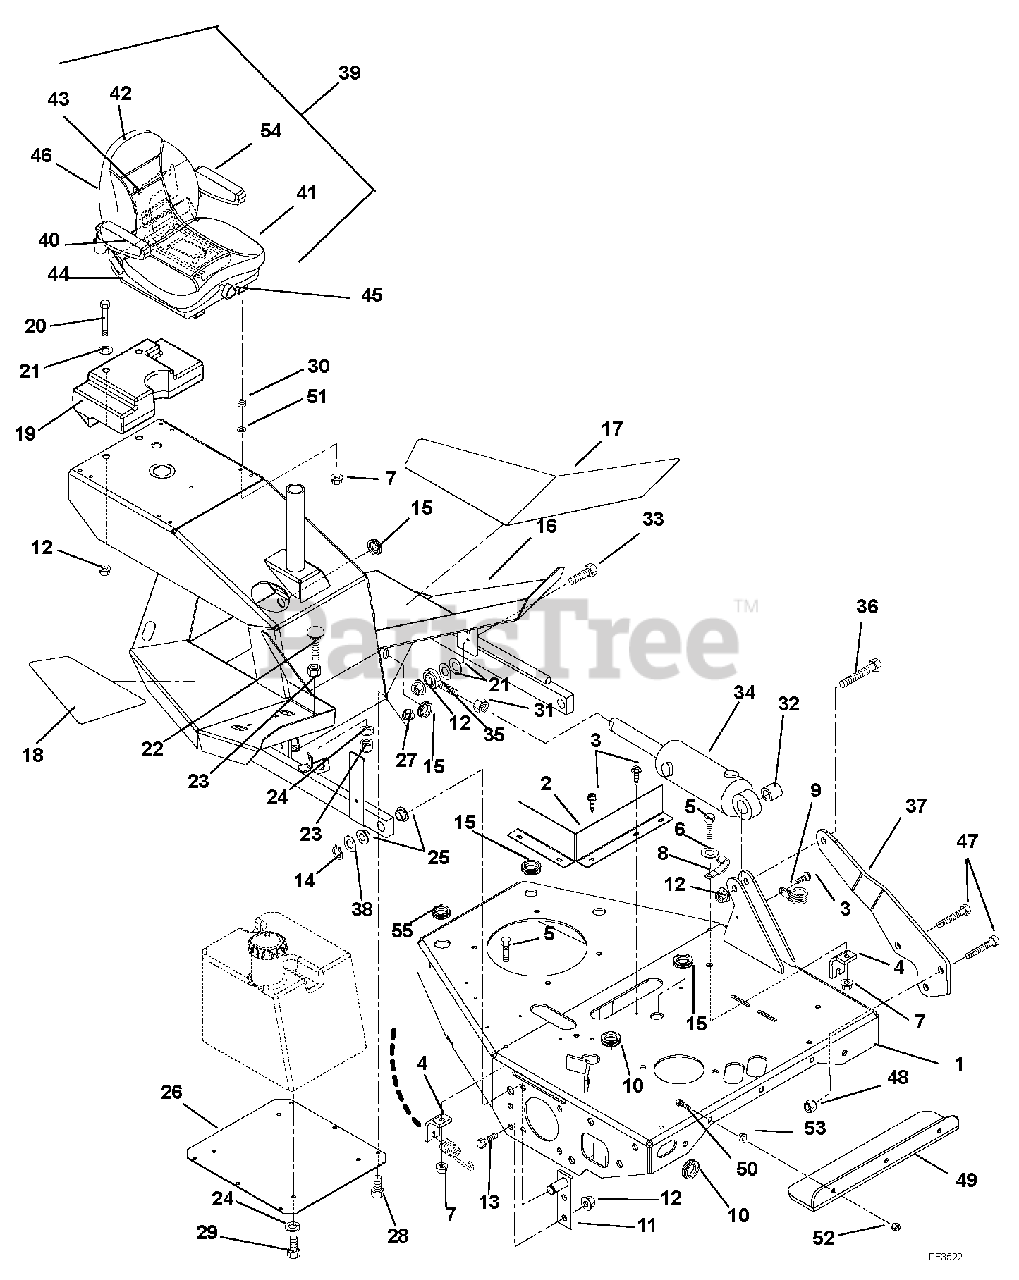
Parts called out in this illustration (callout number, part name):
3	6
5	2
6	1
7	6
12	10
13	4
20	2
21	4
22	1
23	2
24	5
27	6
28	6
29	4
33	1
36	1
50	3
52	3
